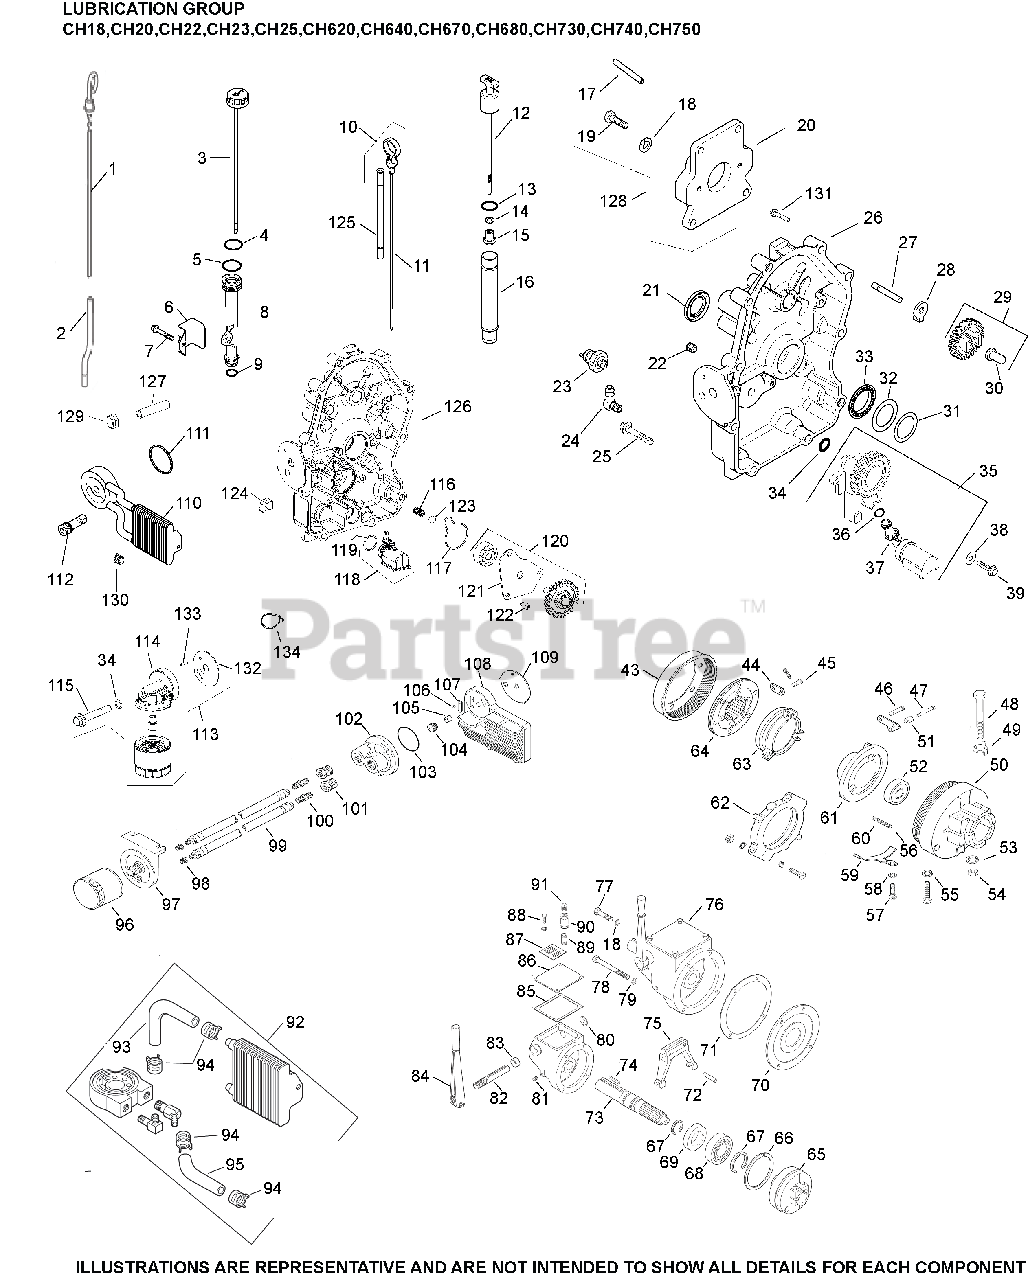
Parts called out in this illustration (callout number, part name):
10	KIT, DIPSTICK/DIPSTICK TUBES
21	SEAL, OIL
22	PLUG, CTSK PIPE 1/8"
23	SENSOR, OIL PSI
25	SCREW, FLG M8X1.25X45
27	SHAFT, GOVERNOR GEAR
28	TAB, LOCKING
29	KIT, GOVERNOR GEAR W/PIN
30	PIN, GOVERNOR REGULATING
40	NUT, PLASTIC - BLACK
41	SCREW, TAP M6X1.7X18
93	KIT, HOSE 140MM
96	OIL FILTER
104	NIPPLE, OIL FILTER
110	COOLER, OIL & DIVERTER ASSEMBLY
111	O-RING, OIL COOLER
113	ADAPTER, OIL FILTER (CV EFI)
116	SPRING, COMPRESSION
117	SEAL, OIL PUMP COVER
118	PICK-UP ASSEMBLY, OIL
119	O-RING, OIL PICK-UP
120	PUMP ASSEMBLY, OIL
121	COVER, OIL PUMP
122	SCREW, BUTTON HEAD
123	PRESSURE RELIEF BALL
126	KIT, CLOSURE PLATE ASSY
130	CLAMP, HOSE LOW PROFILE
131	SCREW, HEX FLANGE
